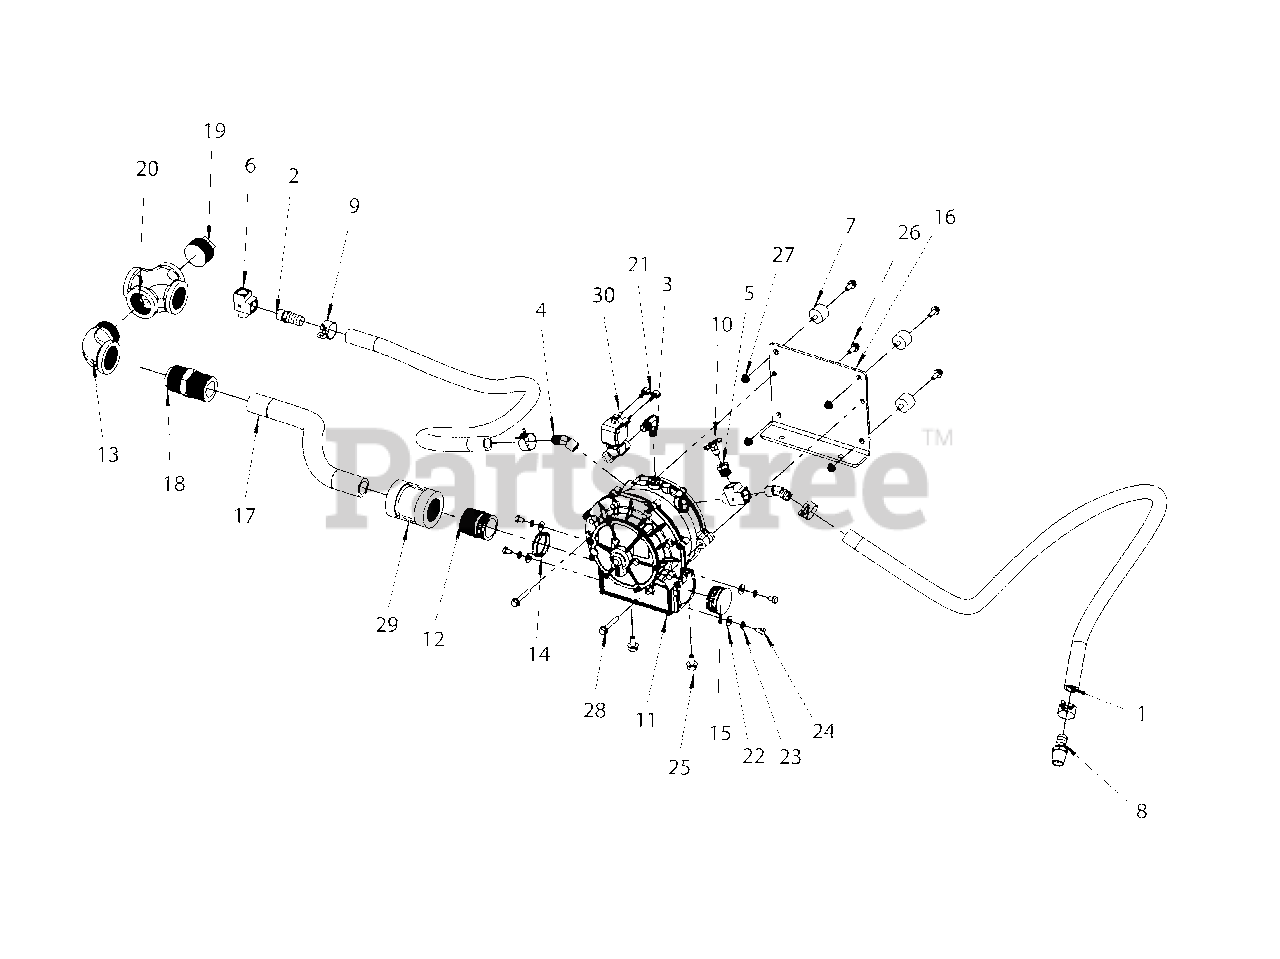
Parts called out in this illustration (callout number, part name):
1	* WATER HOSE - 90 IN
2	* FITTING
3	* FITTING
4	* FITTING
5	* BUSHING
6	* TEE
7	* ISOLATOR
8	* FITTING
9	CLAMP
10	* DRAIN COCK
11	* VAPORIZER
12	* ADAPTER
13	* ELBOW
14	* O-RING
15	* PLUG
16	* PLATE
17	HOSE
18	* ADAPTER
19	* FITTING
20	* FITTING
21	* TERMINAL
22	* WASHER
23	* WASHER
24	* BOLT
25	* BOLT
26	* BOLT
27	* NUT
28	* BOLT
29	* COUPLER
30	LOCK-OFF
